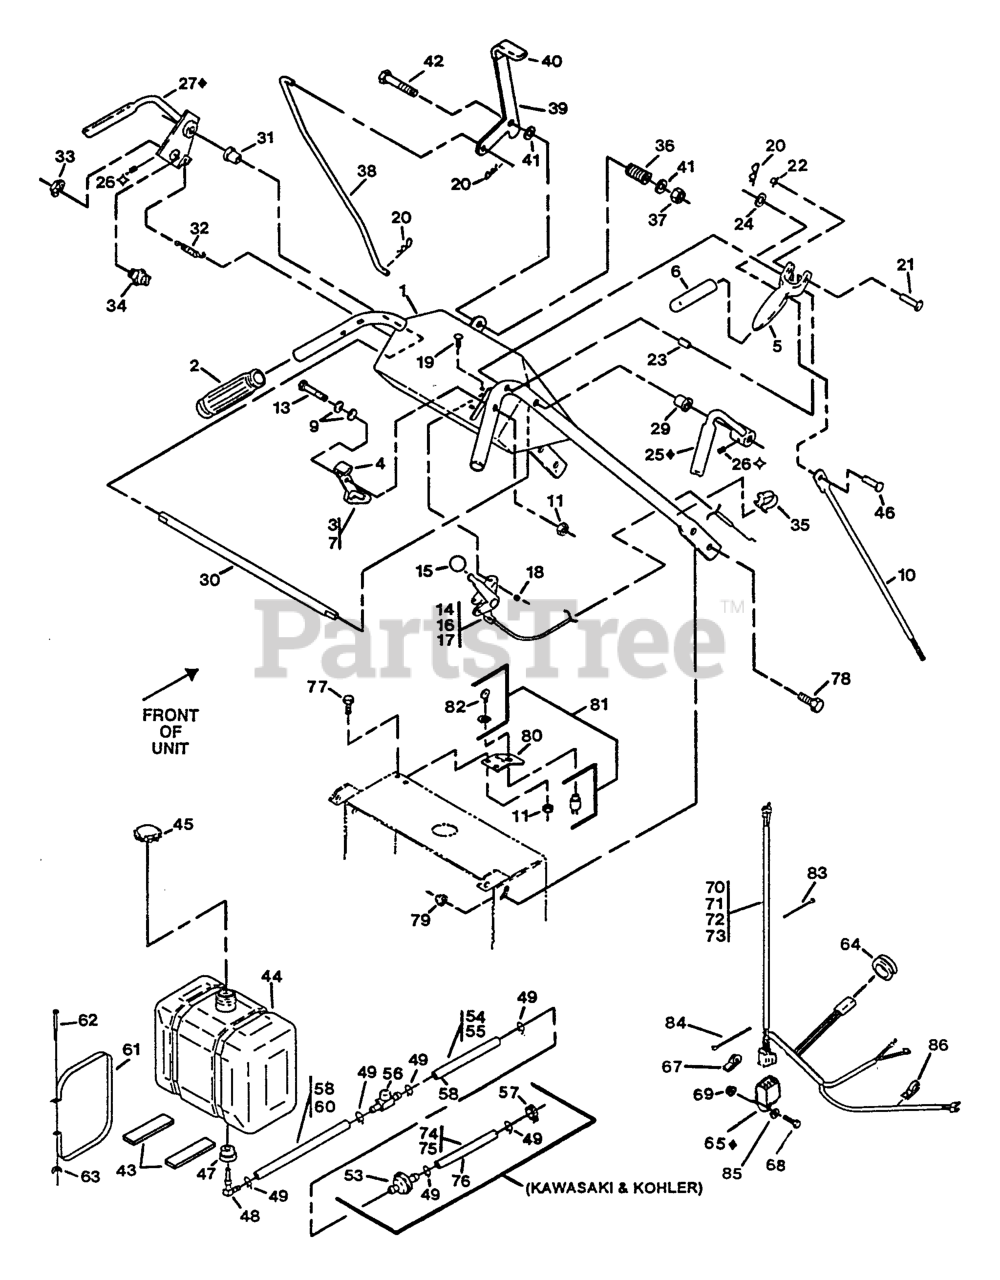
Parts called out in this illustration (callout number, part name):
3	LATCH,W/GRIP LH
4	GRIP-LATCH
5	DRIVE LEVER ASM
6	GRIP-LEVER, DRIVE
7	LATCH,W/GRIP RH
9	WASHER-SPRING
10	LINKAGE-WHEEL, DRIVE
14	CABLE-CONTROL, THROTTLE
15	KNOB-BALL
19	BOLT-CARR
20	PIN-COTTER
21	PIN-LEVER, DRIVE
22	NUT-PUSH
23	PIN-ROLL
26	SCREW-SET
29	BUSHING-NYLON
30	ROD,CONNECTING
31	BUSHING,FLANGED
32	SPRING-EXTENSION
34	SWITCH,OPERATOR CNTRL
35	CLIP-CABLE
36	SPRING-COMPRESSION
38	LINKAGE-BLADE, UPPER
40	GRIP-LEVER
43	PAD,PLASTIC TANK
45	CAP-FUEL
46	PIN,CLEVIS
48	ELBOW-TANK, FUEL
54	HOSE-LINE, FUEL
55	LINE-FUEL
56	VALVE-FUEL
57	CLAMP-HOSE
58	HOSE-FUEL
59	HOSE-FUEL
62	SCRW,MACH CRPH
63	WINGNUT
64	GROMMET
65	MODULE-INTERLOCK
67	CLIP-LOOM
74	HOSE-LINE, FUEL
75	HOSE-FUEL
76	LINE-FUEL
81	SWITCH & KEY (INCLUDES NU
82	KEYS-IGNITION (SPARE PAIR
83	TIE-PLASTIC
84	TIE-CABLE
